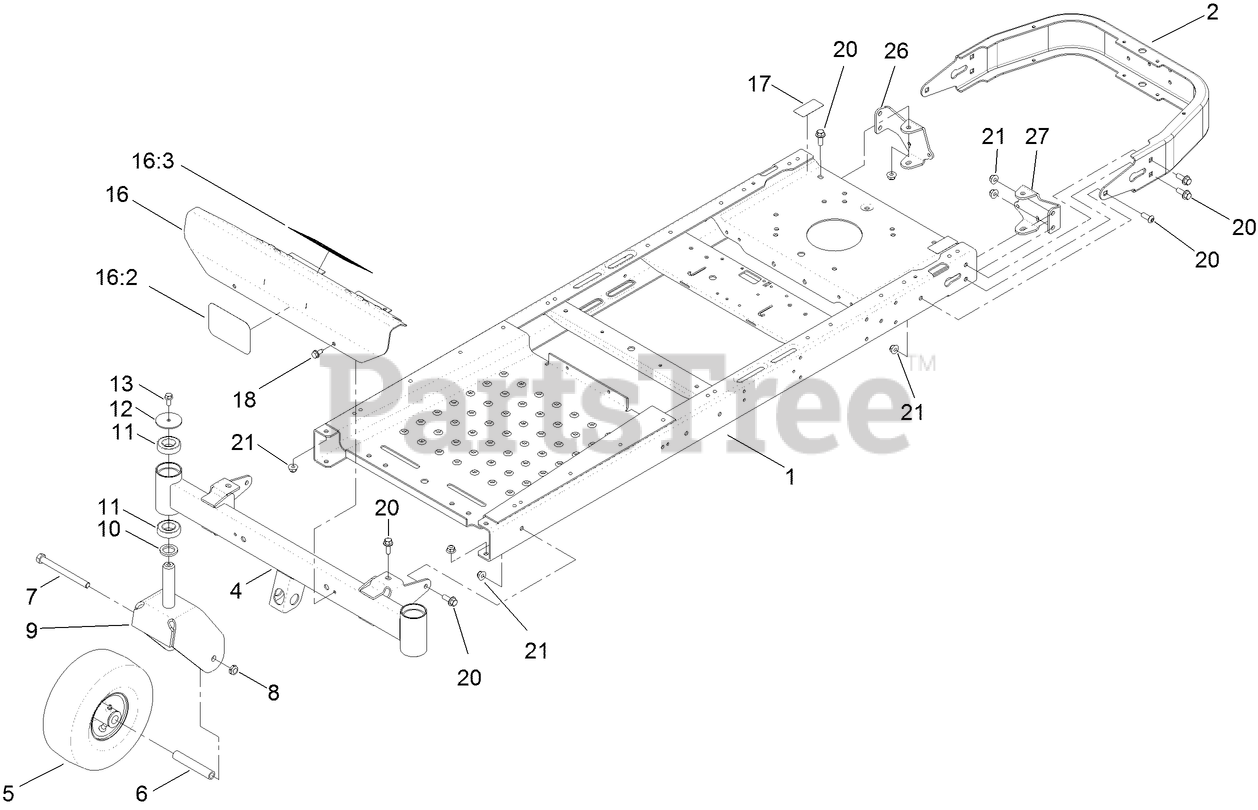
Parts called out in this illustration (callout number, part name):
2	BUMPER-REAR
4	AXLE-FRONT
5	CASTER WHEEL ASM (CST)
6	BUSHING-SPANNER
7	SCREW-HH
8	NUT-HEX
9	FORK-CASTER
10	WASHER-THRUST
11	BEARING-BALL
12	WASHER
13	SCREW-HHF
17	DECAL-BYPASS
18	SCREW-HWHTF
20	SCREW-HHF
21	NUT-HF, NI
26	MOUNT-HYDRO, REAR (RH)
27	MOUNT-HYDRO, REAR (LH)
